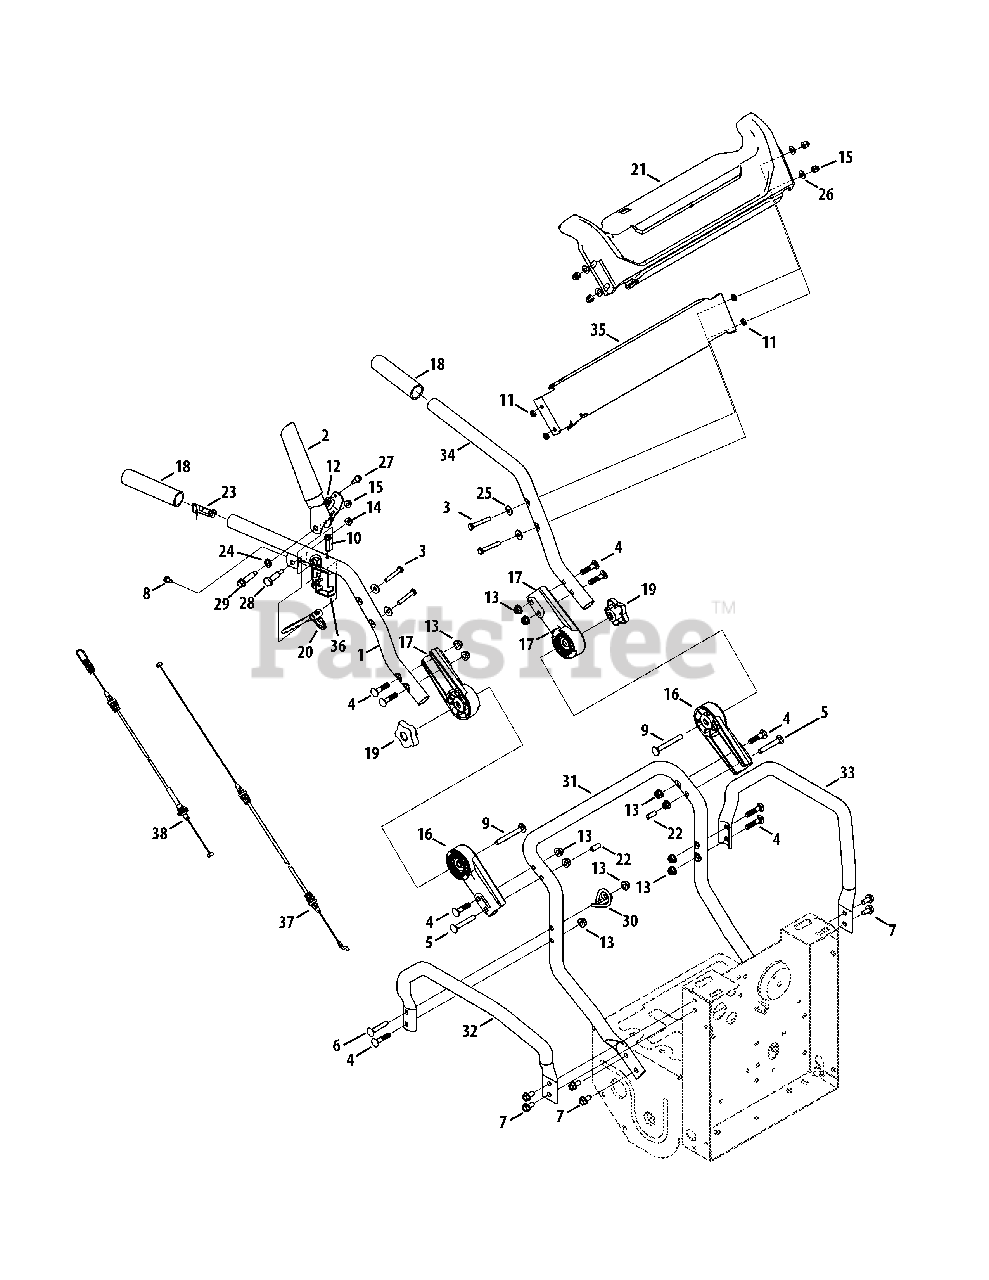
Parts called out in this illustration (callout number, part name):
1	Upper Handle Assembly, RH
2	Lever Assembly, RH
3	Hex Cap Screw, 1/4-20 x 1.75
4	Carriage Bolt, 5/16-18 x 1.50
5	Carriage Screw, 5/16-18 x 2.25
6	Carriage Bolt, 5/16-18 x 1.75
7	Self Tapping Screw, 5/16-18 x .750
8	Hex Washer Screw, 1/4-20 x .500
9	Carriage Bolt, 5/16-18 x 2.75
10	Self-tapping Screw, 1/4-20 x 1.25
11	Jam Nut, 1/4-20
12	Nut, 1/4-28, Lock
13	Flange Lock Nut, 5/16-18
14	Flange Lock Nut, 1/4-20
15	Cap Lock Nut, 1/4-20
16	Lower Handle Adjustment
17	Upper Handle Adjustment
18	Grip, 1.0 x 5.0
19	Star Knob, 5/16-18
20	Drive Lever
21	Handle Cover
23	Spring, Button Plug
24	Flat Washer, .385 x .62 x .063
25	Bell Washer, .265 x .75 x .062
26	Flat Washer, .250 x .630 x .052
27	Shoulder Bolt, 1/4-28 x .342 x .335
28	Shoulder Screw, .374 x 1.16
29	Shoulder Screw,, 1/4-20 x .375 x 1.355
32	Frame Tube, RH
33	Frame Tube, LH
34	Upper Handle, LH
35	Handle Panel
36	Cable Support Bracket
37	Engagement Cable
38	Drive Cable
